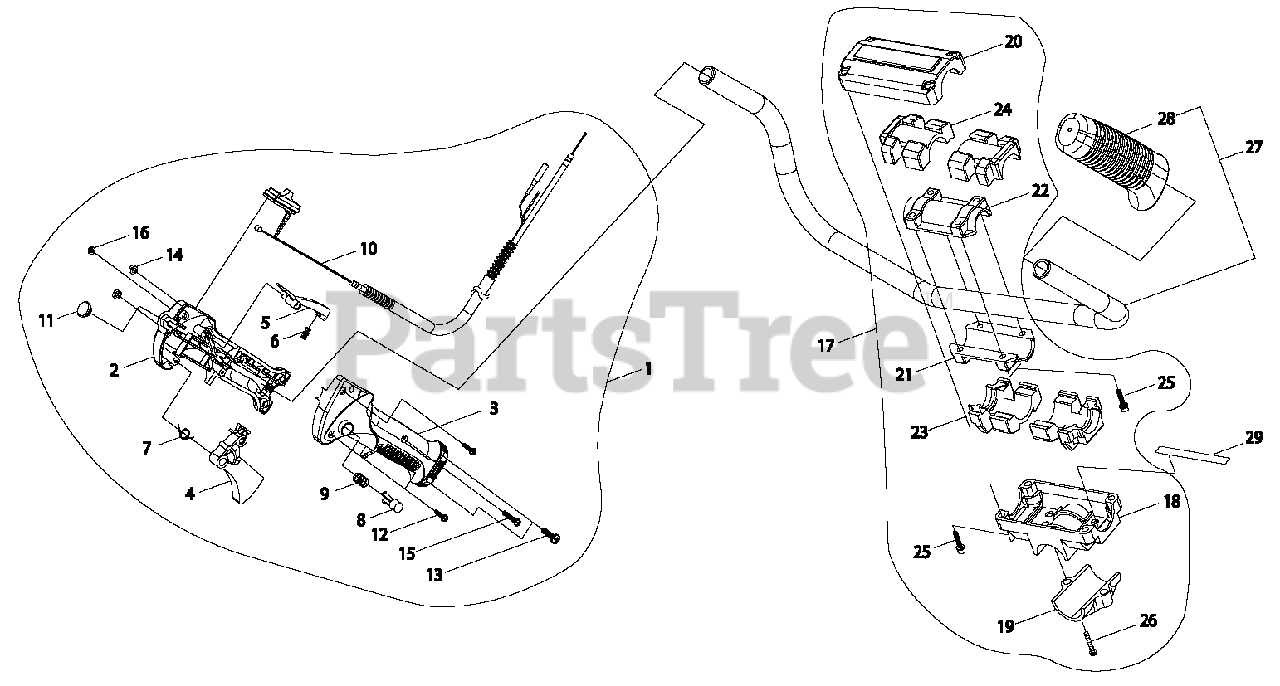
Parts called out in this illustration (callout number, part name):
1	THROTTLE CONTROL ASSY
2	CONTROL HANDLE - RIGHT
3	CONTROL HANDLE - LEFT
4	TRIGGER, THROTTLE
5	LOCKOUT, THROTTLE
6	SPRING, COMPRESSION
7	SPRING, TORSION
8	BUTTON, THROTTLE LOCK
9	SPRING, COMPRESSION
10	CABLE ASSY, CONTROL
11	PLUG, RUBBER
12	SCREW, TAPPING 4×16
13	SCREW M5×20
14	NUT M5
15	SCREW M4×23
16	NUT M4
17	BRACKET KIT, HANDLEBAR
18	BRACKET, LOWER
19	BRACKET, MOUNTING
20	BRACKET, UPPER
21	CLAMP, LOWER
22	CLAMP, UPPER
23	CUSHION, LOWER
24	CUSHION, UPPER
25	BOLT M5×25
26	SCREW M6×25
27	HANDLEBAR ASSY
28	GRIP
29	LEAD - GROUND
